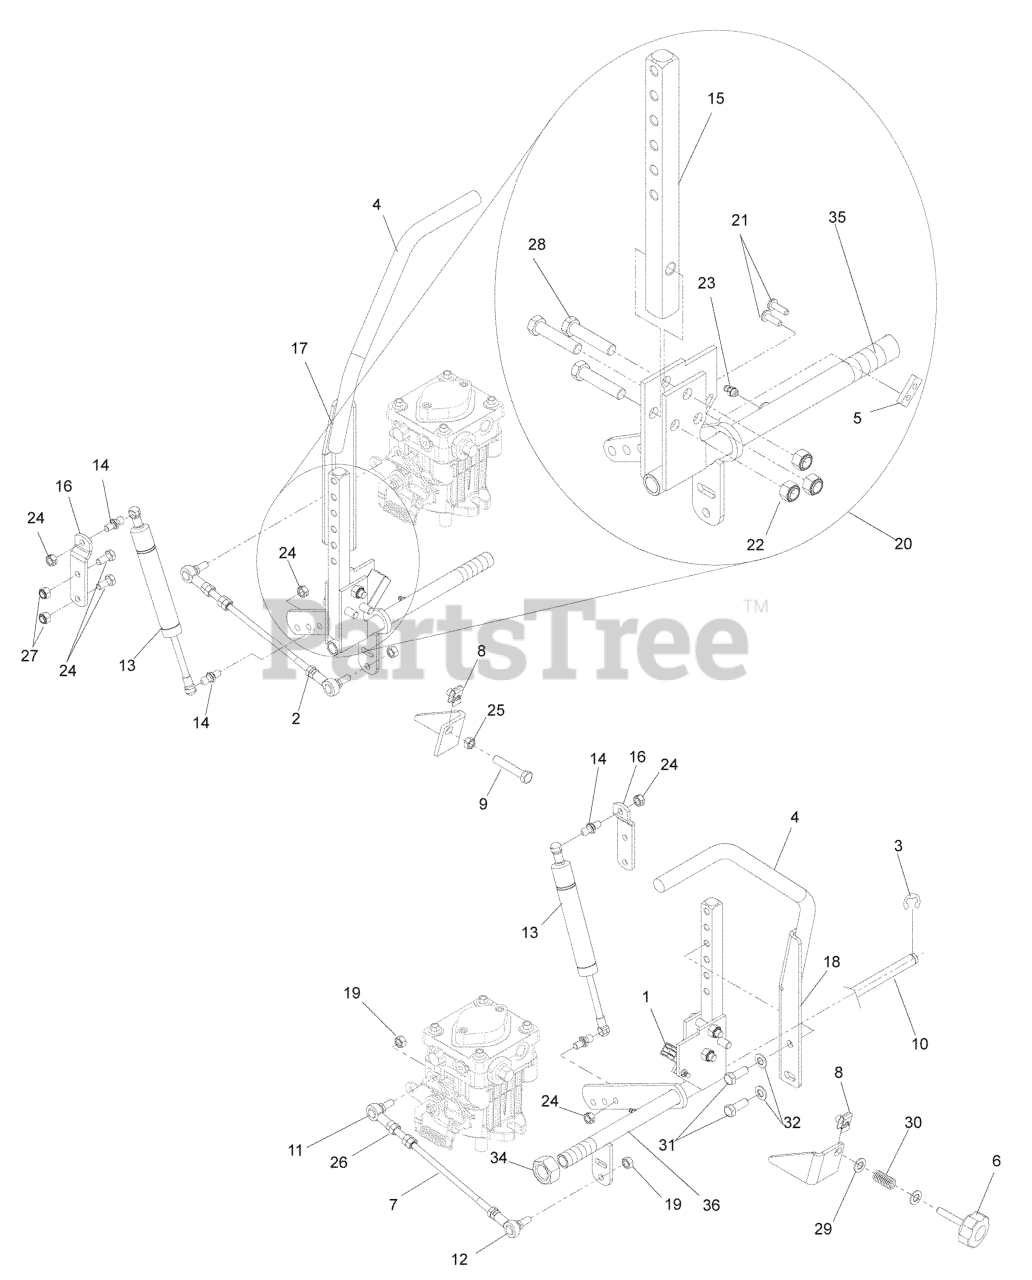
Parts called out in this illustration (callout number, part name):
1	SWITCH, INTERLOCK
2	NUT 5/16F LEFTHAND
3	E-RING 1/2 (2 2)
4	GRIP - DRIVE LEVER 12"
5	TAPPED PLATE
6	ADJUSTMENT KNOB
7	PUMP CONTROL LINK
8	U-CLIP 5/16-18 NUT RETAINER
9	HCS 5/16-18X1-3/4 TPBLT
10	CONTROL SHAFT
11	SPHERICAL ROD END, RH
12	SPHERICAL ROD END, LH
13	DAMPENER W/EXT SEAL
14	STUD.BALL.10MM
15	CONTROL ARM
16	DAMPENER ARM
17	ASSEMBLY, DRIVE LEVER RT
18	ASSEMBLY, DRIVE LEVER LT
19	NUT 5/16F NYLOC
20	CONTROL ASM, RT
22	NUT 3/8-16 NYLOC
23	ZERK
24	NUT 5/16C CENTERLOCK
25	NUT 5/16C HEX
27	NUT 5/16 NYLOC
28	HCS 3/8-16 X 1 3/4 GR5
29	WASHER 5/16 FLAT
30	COMPRESSION SPRING
31	HCS 3/8-16X1.GRD.5.ZD
32	WASHER, 3/8 DISC SPRING SPEC
33	HCS 5/16C X 3/4
34	NUT 3/4 X 16 HEX CTR
35	DRIVE CONTROL, RT
36	DRIVE CONTROL, LT
